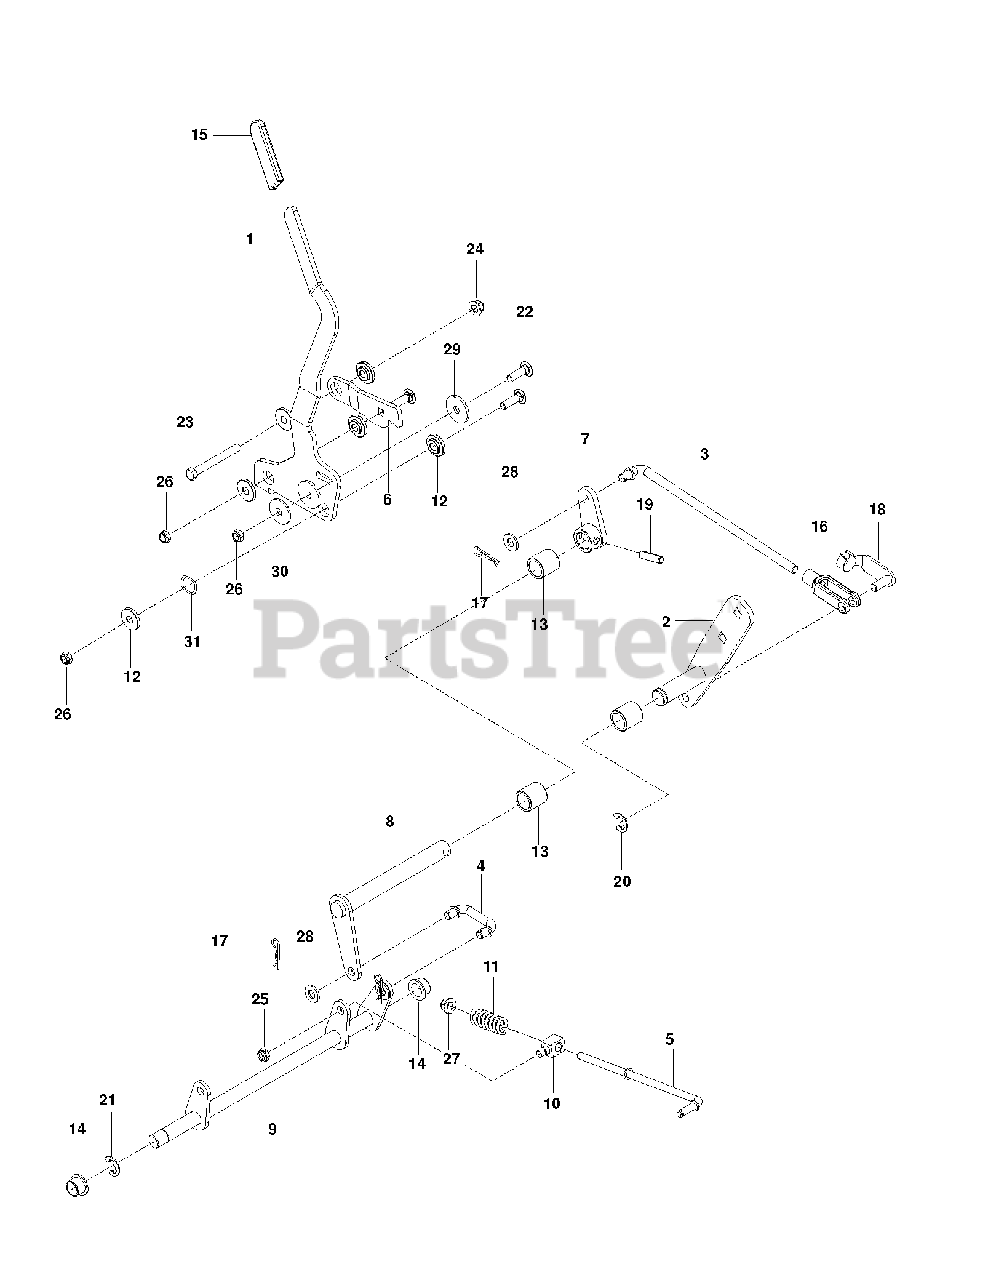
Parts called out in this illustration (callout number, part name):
1	LEVER, BRAKE, BLK
6	LINK, FOLLOWER
7	ARM, RT BRAKE
10	SWIVEL, BRAKE
12	BUSHING, BRAKE
13	BUSHING, SLEEVE 3/4 X 1.0
17	HAIRPIN #2
18	PIN, CLEVIS SPRING, 3/8
19	5/16 DIA ROLL PIN
20	E RING 3/4
21	5/8 E-RING
22	RHSNB 3/8-16 X 1-1/4
23	HCS 3/8-16 X 3-1/4 GR5 ZD
24	NUT 3/8-16 HEX FLG NYLOC ZD
25	5/16-18 THIN PROF NY
26	NUT HEX 3/8-16 NYLON, THIN
27	5/16-18 NYLOC FLANGE NUT
28	WASHER 3/8 SAE FLAT
29	WASHER, FRICTION, 1/8
31	WASHER, .825 X 1.087, WAVE
